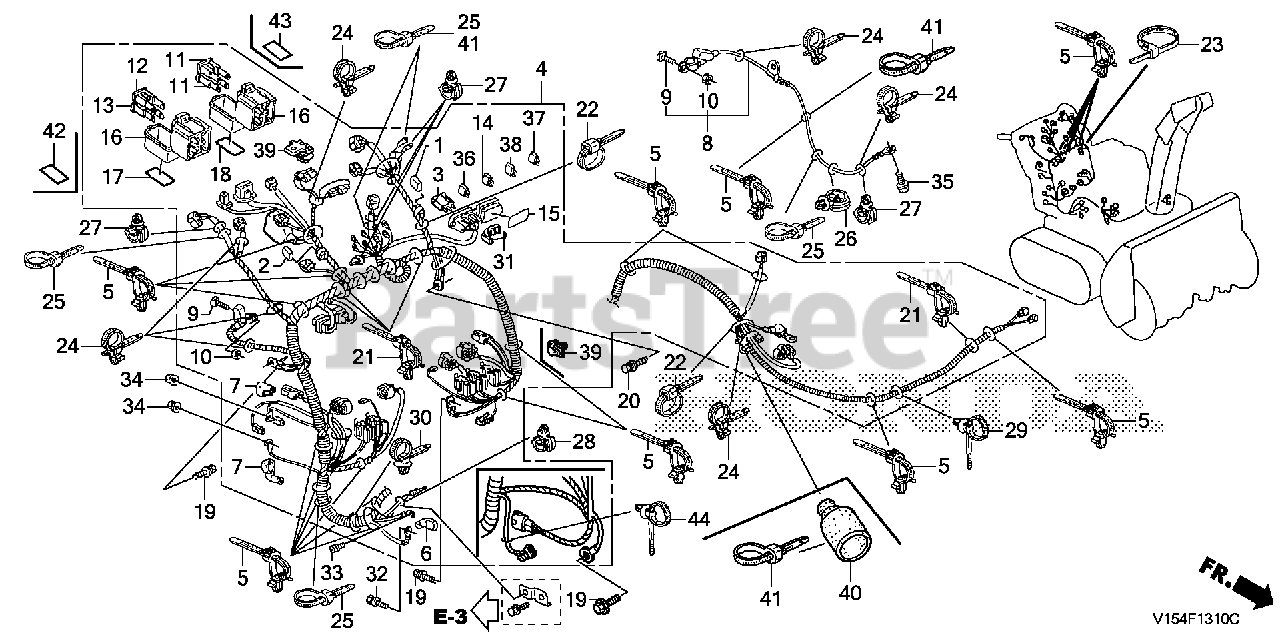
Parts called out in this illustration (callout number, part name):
4	WIRE HARNESS ASSY., MAIN
5	BAND, WIRE HARNESS
8	CABLE ASSY., GROUND
9	BOLT, BATTERY TERMINAL
10	NUT, BATTERY TERMINAL
11	FUSE (80A) (BLOCK)
12	FUSE, BLOCK (70A)
15	LABEL, BLADE FUSE
16	CASE, MAIN FUSE
17	MARK, MAIN FUSE
18	MARK, MOTOR FUSE
19	BOLT, GROUND (6X16) (WASHER 12.5MM) (ZN)
20	BOLT (6X19 SN)
21	BAND, WIRE HARNESS (150MM) (NATURAL)
22	BAND, WIRE (95MM)
24	STRAP, CABLE (105MM) (BLACK)
25	BAND, SUCTION HOSE (BLACK)
27	CLIP, WIRE HARNESS (25MM)
29	CLIP, WIRE HARNESS (110MM) (7MM HOLE) (GREEN)
31	CLIP, CONNECTOR HOLDER (BROWN)
35	BOLT, FLANGE (6X10)
36	FUSE, MINI (5A)
37	FUSE, MINI (15A)
39	CLIP, CONNECTOR (DARK GREEN)
40	COVER, CONNECTOR (NOT AVAILABLE)
41	BAND, WIRE (165MM) (BLACK)
44	CLIP, HARNESS BAND (145MM) (BLACK)
